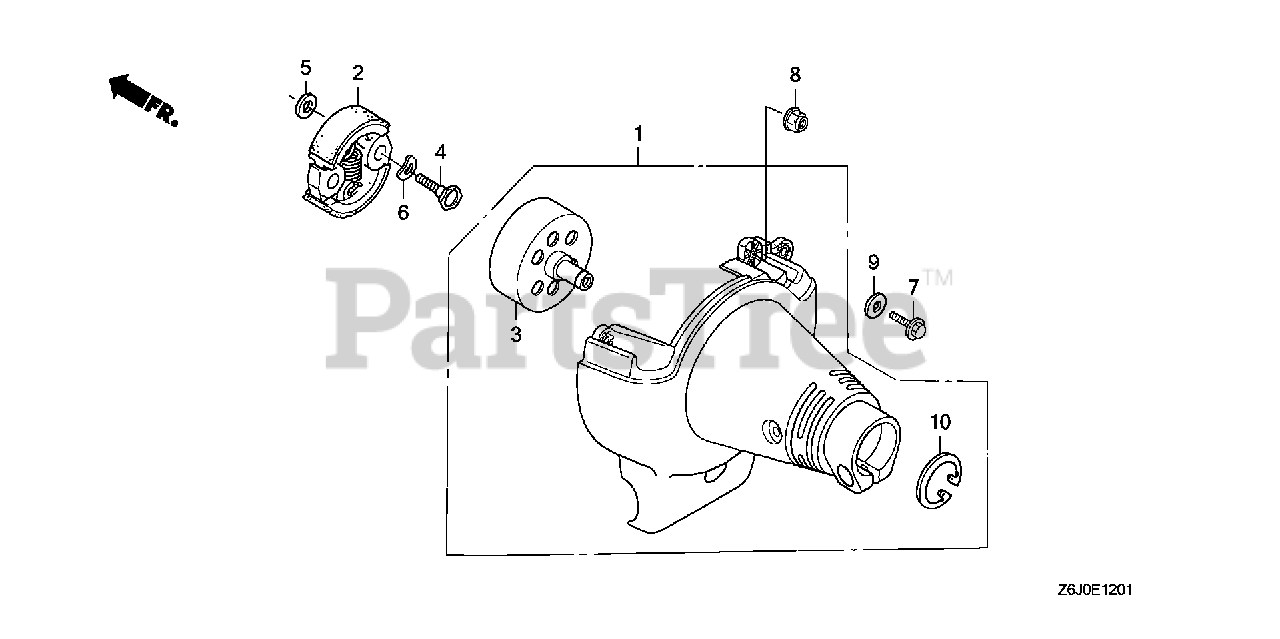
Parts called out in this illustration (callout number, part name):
1	COVER ASSY., FAN
2	CLUTCH ASSY.
3	CLUTCH OUTER
4	BOLT, CLUTCH (6MM)
5	WASHER, CLUTCH (6X15)
6	WASHER, WAVE (8MM)
7	BOLT, SOCKET (5X20)
8	NUT, SPECIAL (4MM)
9	WASHER, PLAIN (5MM)
10	CIRCLIP (OUTER) (10MM)
